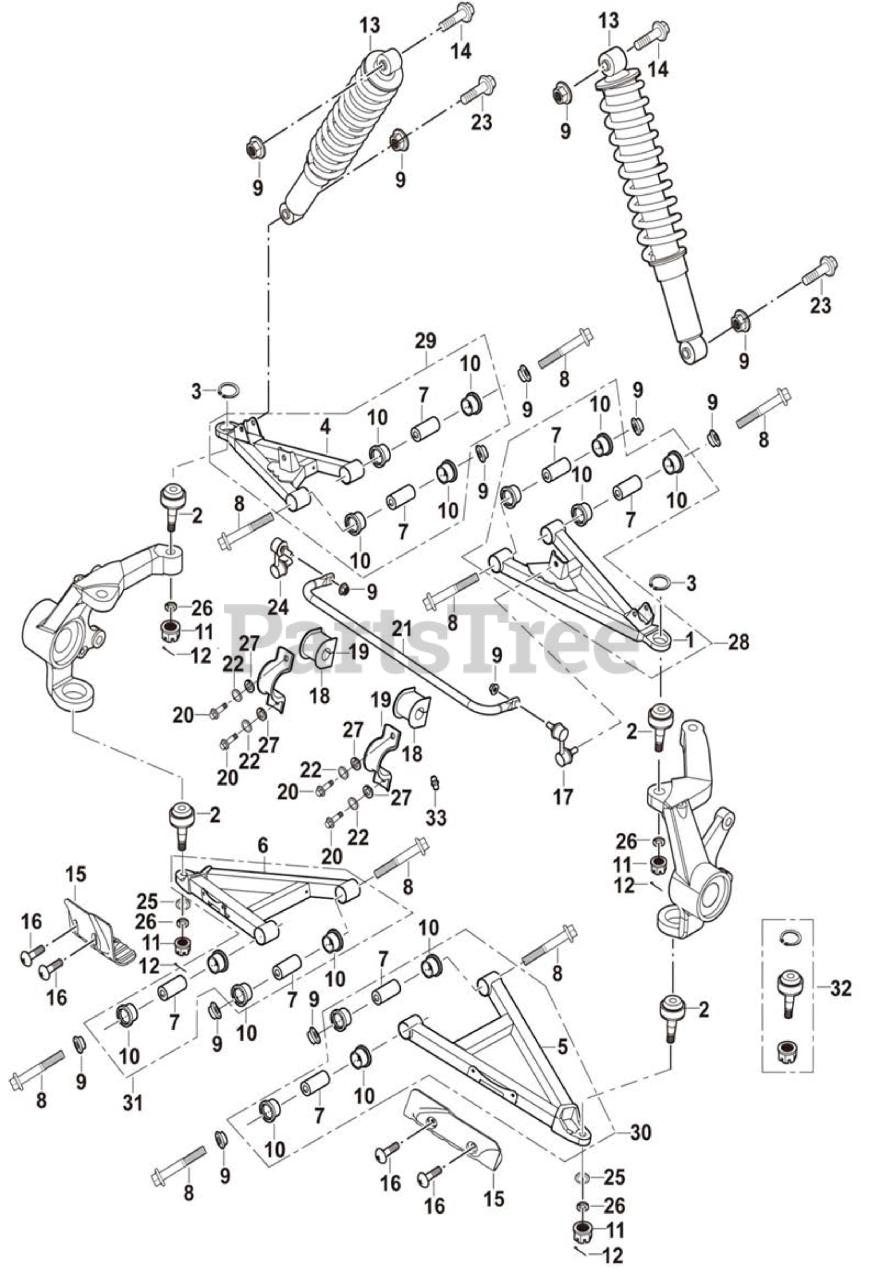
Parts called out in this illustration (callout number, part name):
1	Front-Upper Suspension (L)
2	Universal Joint E
3	Elasticity Block Ring d=30
4	Front-Upper Suspension (R)
5	Front-Lower Suspension (L)
6	Front-Lower Suspension (R)
7	Bush 10.3X23X50
8	Hexagon Flange BoltM10X1.25X75
9	Hexagon Flange Self-Lock Nuts M10x1.25
10	Bush 22X28
11	hexagon thin slotted nut M12X1.25
12	Cotter pin 2.5X30
13	Front Shock Absorber D
14	Hexagon Flange BoltM10X1.25X50
15	Front cradle backplate
16	Cross Large Plate Head Screw M6X12
17	Ball joint,left balancing lever
18	damped adhesive,balancing lever 20X45
19	mounting cap,cushion rubber
20	Hexagon Flange Bolt M8X30
21	Anti-roll Bar, Front Suspension
22	Spring Washer-8
23	Hexagon Flange Bolt M10X1.25X75
24	Ball joint,right balancing lever
25	Flat Washer 12.5X24X2
26	Spring Washer 12
28	Front left upper rocker arm
29	Front right upper rocker arm
30	Front left lower rocker arm
31	Front right lower rocker arm
32	Front Knuckle Ball Joint
33	Swing arm nozzle
